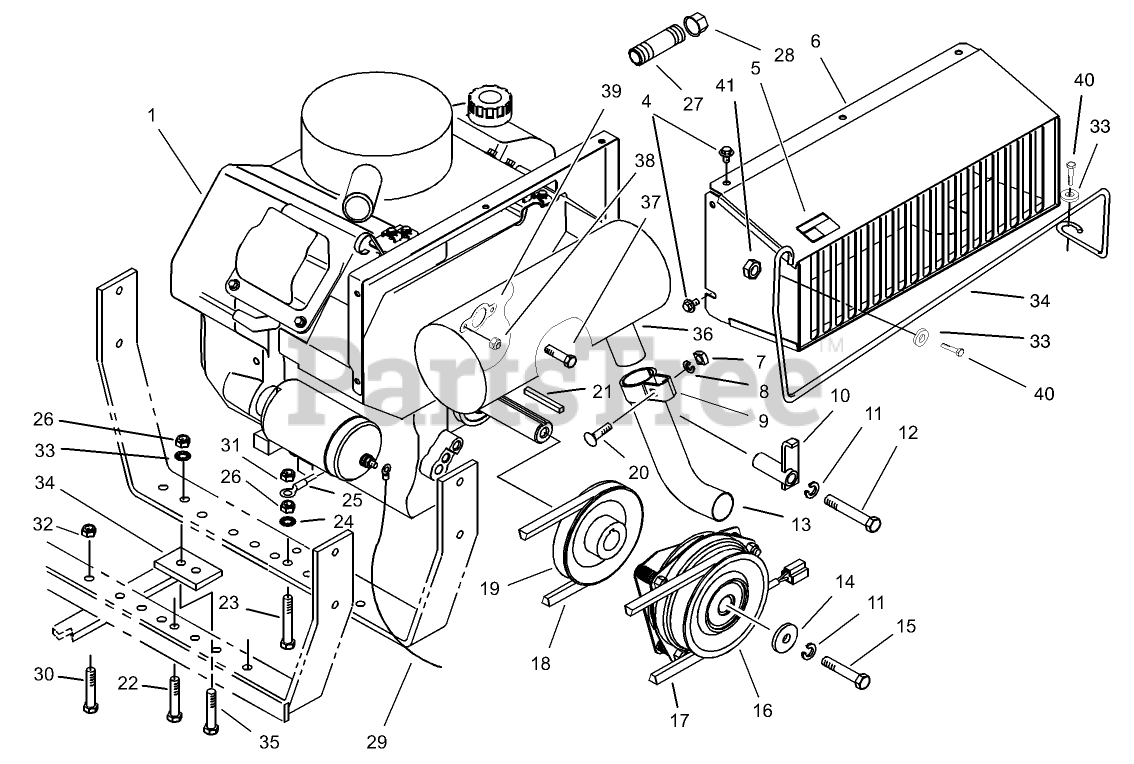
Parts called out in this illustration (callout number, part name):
1	Engine-Kohler 20 HP Model CH20QS PS 64556
4	SCREW
5	DECAL-SURFACE, HOT
6	Duct-Engine
7	NUT-HEX
8	WASHER-LOCK
9	Clamp Assembly (Incl. Ref. #7, 8 & 20)
10	Anchor Bracket
11	WASHER-LOCK
12	SCREW-HH
13	EXHAUST PIPE
14	WASHER-CLUTCH
15	SCREW-HH
16	BRAKE CLUTCH ASM
17	V-BELT, JACKSHAFT
18	V-BELT, TRACTION
19	ENGINE PULLEY
20	SCREW-CARR
22	SCREW-HH
23	SCREW-HH
24	WASHER-LOCK, INTERNAL
25	WIRE ASM (NEGATIVE)
26	NUT-LOCK, NI
27	NIPPLE-PIPE
28	CAP-PIPE
29	POSITIVE WIRE ASM
30	SCREW-HH
31	NUT-HHF, WHIZ
32	NUT-HF
33	WASHER-PLAIN
34	Guard-Tank
35	SCREW-HH
36	Muffler
37	SCREW-HHF
38	Nut-Lock
39	GASKET-EXHAUST
40	SCREW-HH
41	NUT-LOCK, NI
